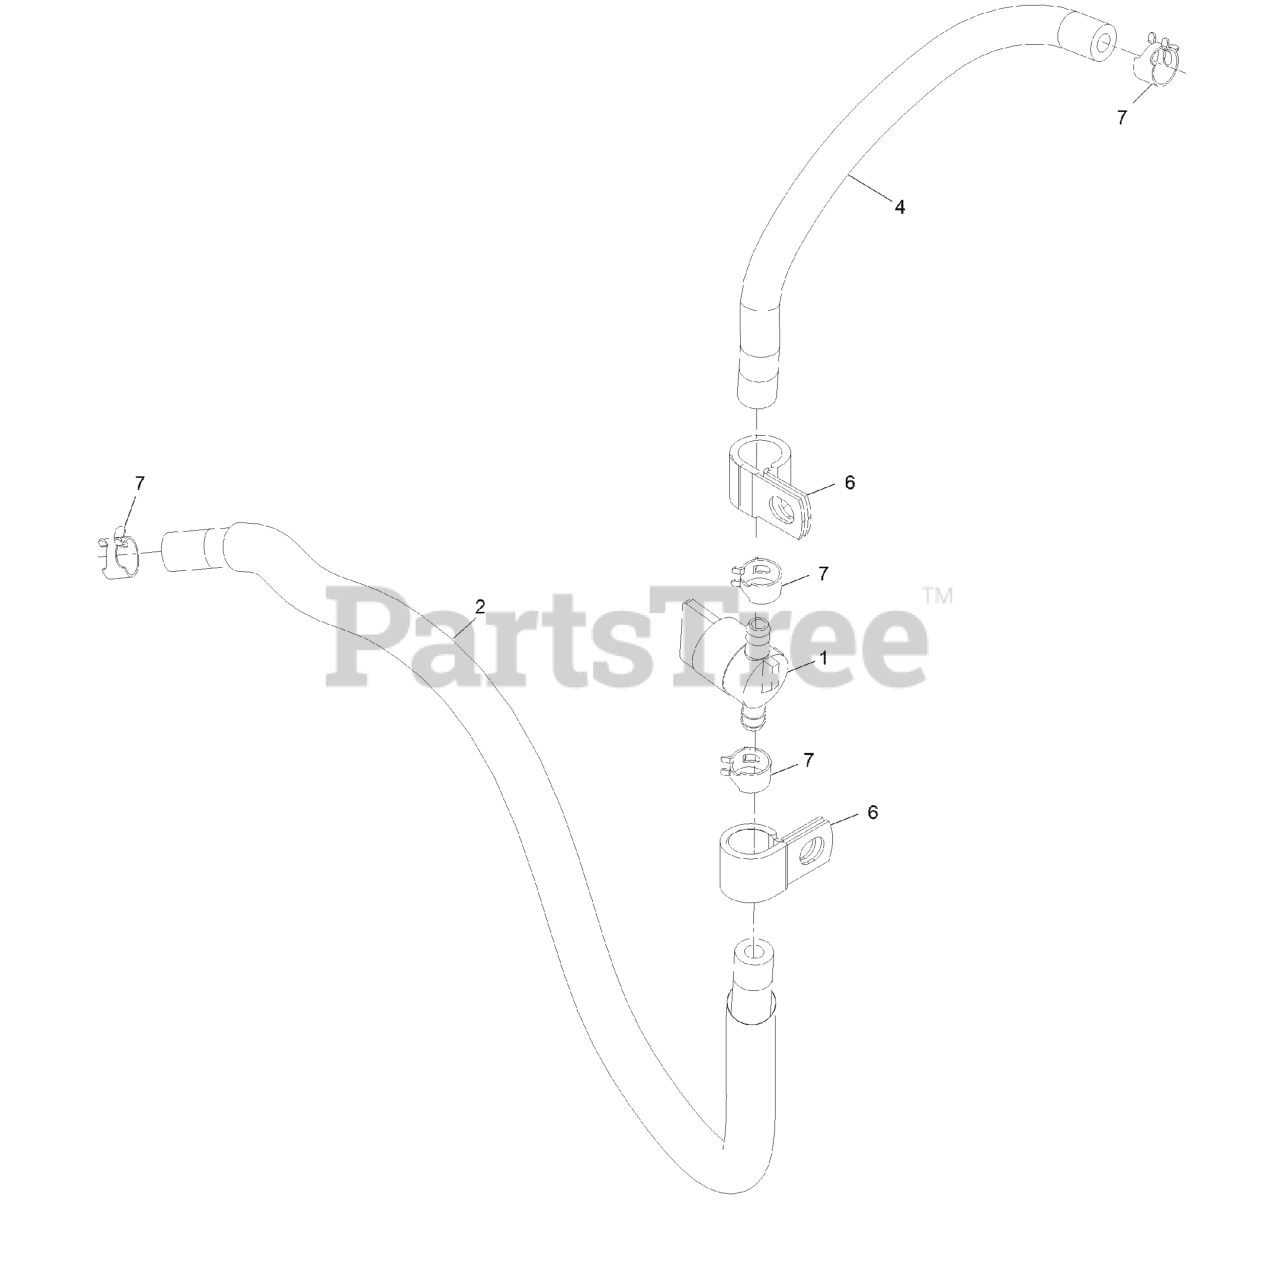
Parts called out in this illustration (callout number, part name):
1	VALVE-FUEL
2	HOSE-FUEL
4	HOSE-FUEL
6	CLAMP-R
7	CLAMP-HOSE
